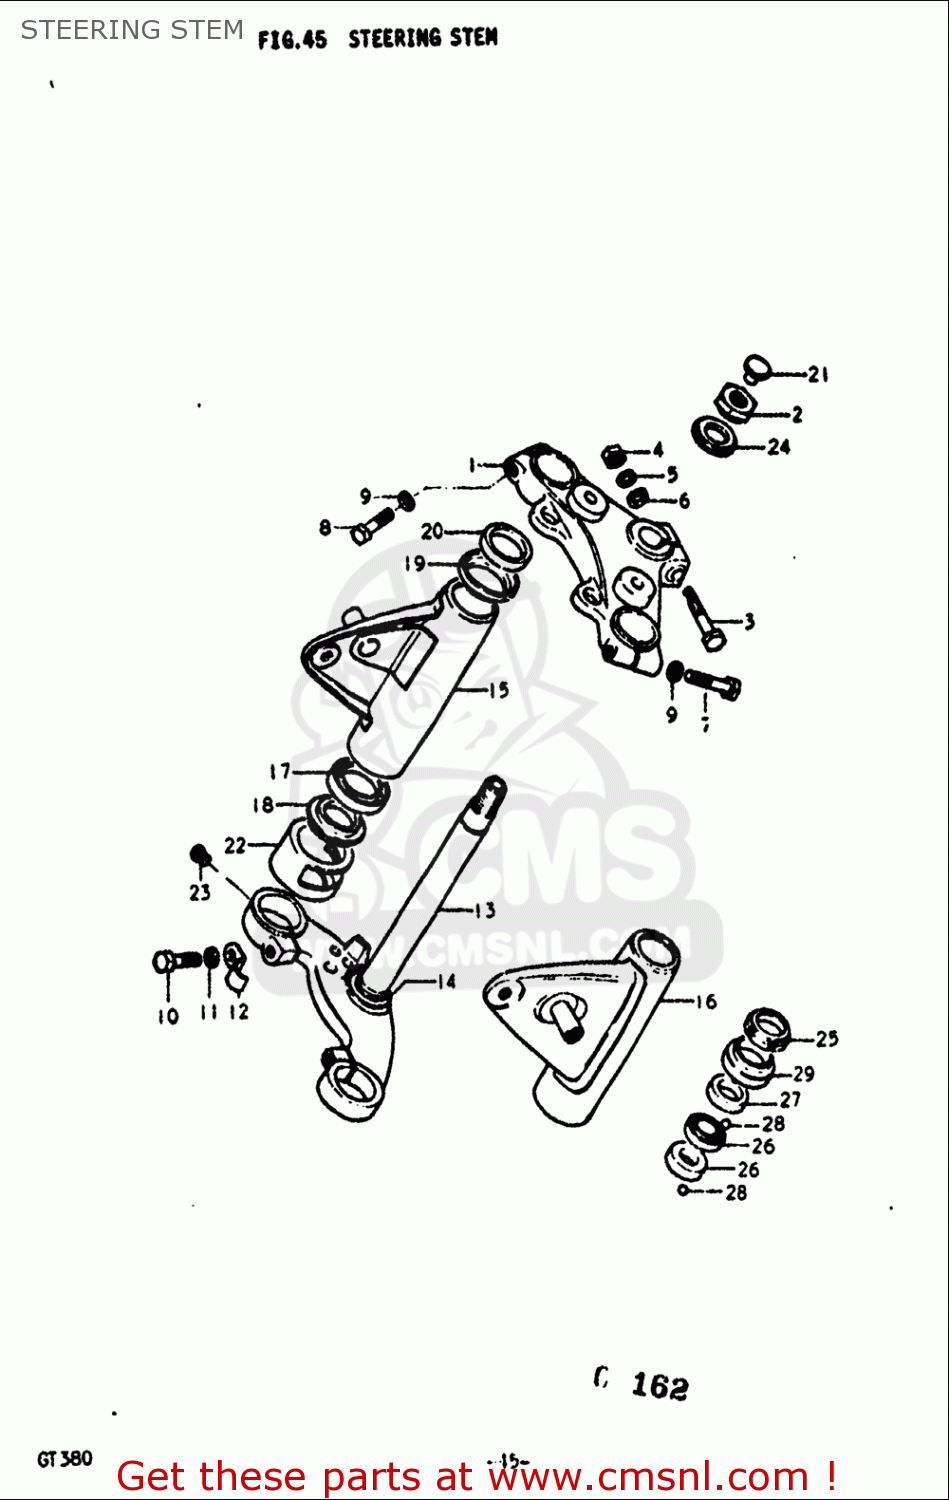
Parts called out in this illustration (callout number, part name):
2	NUT
3	BOLT
4	NUT
5	WASHER,LOCK
6	WASHER
7	BOLT
9	WASHER,LOCK
10	BOLT
11	WASHER,LOCK
12	CLIP,SPEEDOMETER CABLE
14	RACE,STEERING OUTER LWR
17	GUIDE
18	CUSHION,HEADLAMP BRACKET
19	GUIDE
20	CUSHION,HEADLAMP BRACKET UPR
21	CAP(OD:20)
22	COVER,FORK LWR BRACKET
23	SCREW(5X6)
24	WASHER
25	NUT,STEERING STEM(25X44X10)
26	LACE,STEERING INNER LWR
27	LACE,STEERING OUTER UPR
28	BALL
29	DUST SEAL,STEERING UPR
